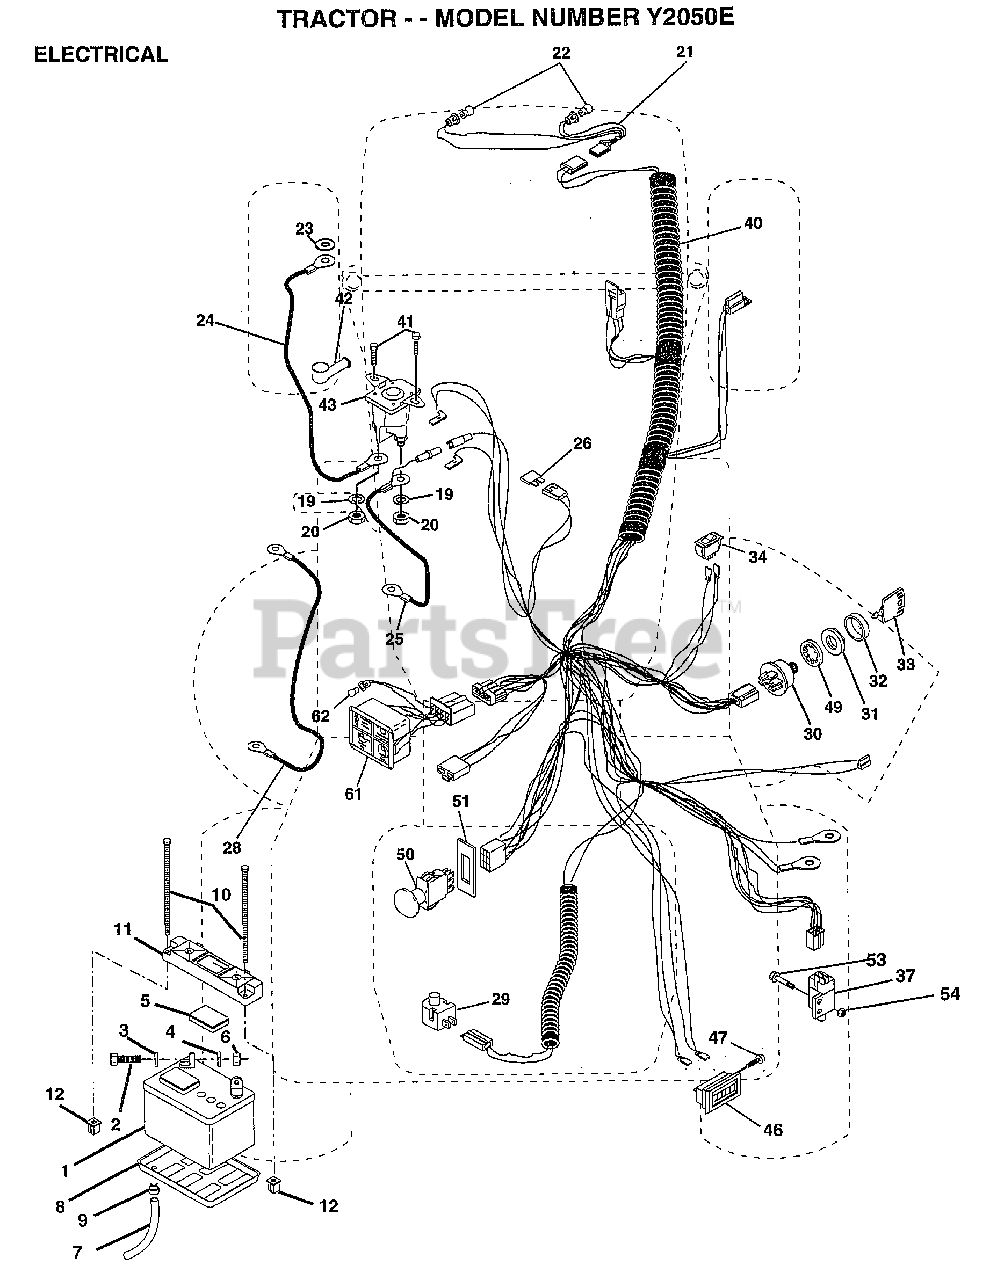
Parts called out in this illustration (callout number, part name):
2	BOLT LT
3	LOCKWASHER
4	WASHER
5	"CAP,BATTERY "
7	"DRAIN TU T, BATT"
8	"TRAY T, BATTERY"
9	HOSE CLAMP T
20	NUT
21	"HARNESS,LIGHT SOC"
22	HEADLAMP BULB
23	LOCKWASHER
24	"CABLE T, BATTERY"
25	CABLE.6GA.12.5.
26	FUSE HYT
28	CABLE T
29	SWITCH SEAT
32	COVER KEY SWITCH
33	KEY MLD GEN DELTA
34	SWITCH LT
37	SWITCH INTERLOCKT
40	HARNESS.IGN.GT.EL
41	SCREW
46	HOUR METER T
47	SCREW
51	RING RETAIN PTO
53	SCREW
54	"NUT,KEPS"
61	LIGHT.PKG.ASM.
62	BULB LIGHT T
